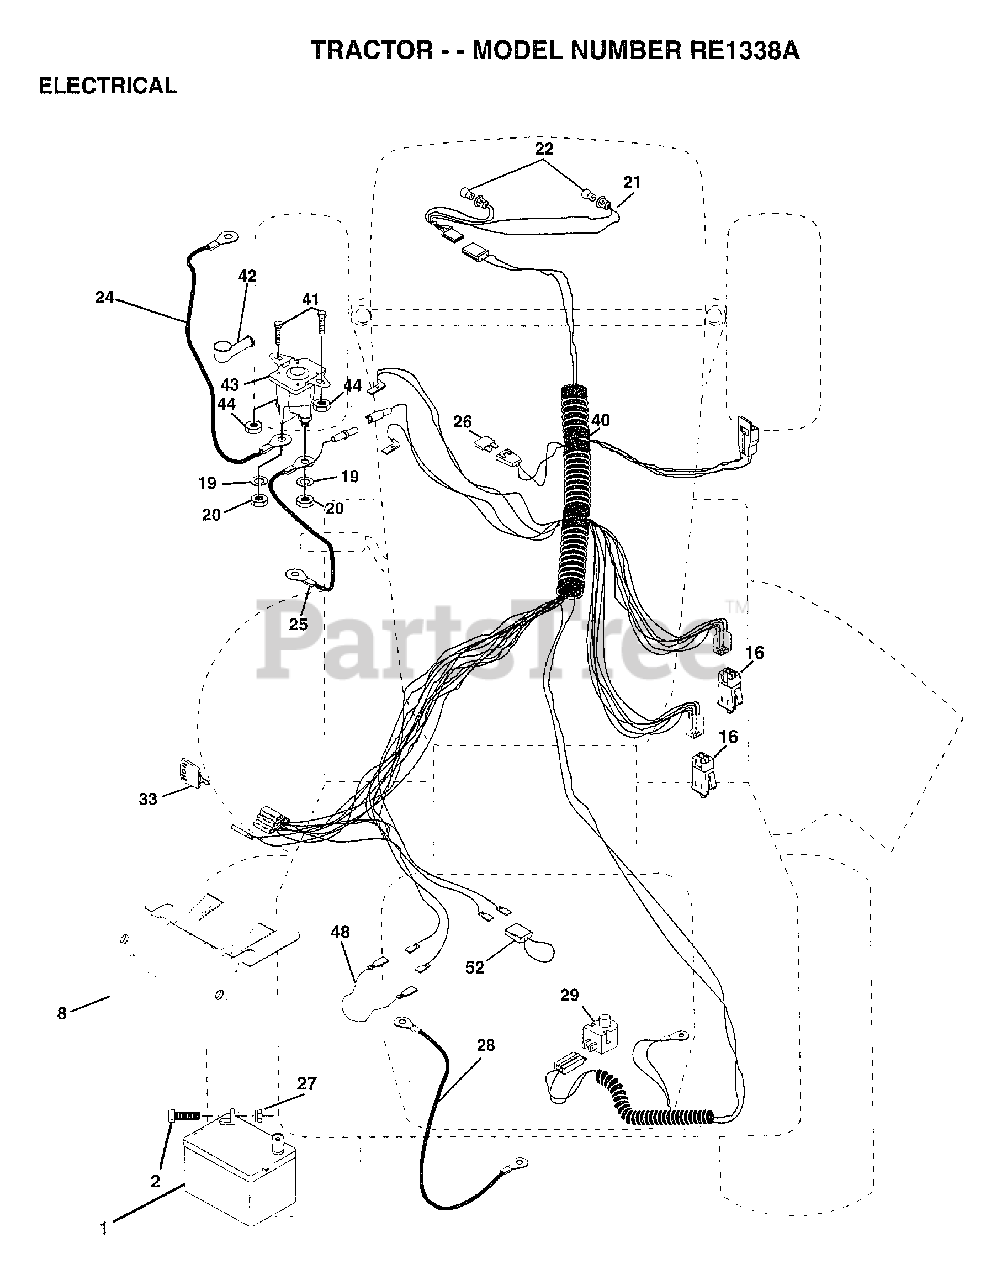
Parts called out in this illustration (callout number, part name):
2	BOLT LT
8	"CASE,BATTERY.MECH"
16	SWITCH INTERLOCK
20	NUT
21	HARNESS.ASM.LIGHT W/4152J
22	HEADLAMP BULB
24	CABLE ASM.
25	CABLE.BTRY.6GA.RD
26	FUSE HYT
27	NUT
28	CABLE T
29	SWITCH SEAT
30	SWITCH.IGN.
33	KEY MLD GEN DELTA
40	IGNITION.HARNESS/MECH
41	BOLT HXHD FIN
44	NUT HXKEP 1/4X20
48	ADAPTER AMMETER
52	PROTECTION LOOP
